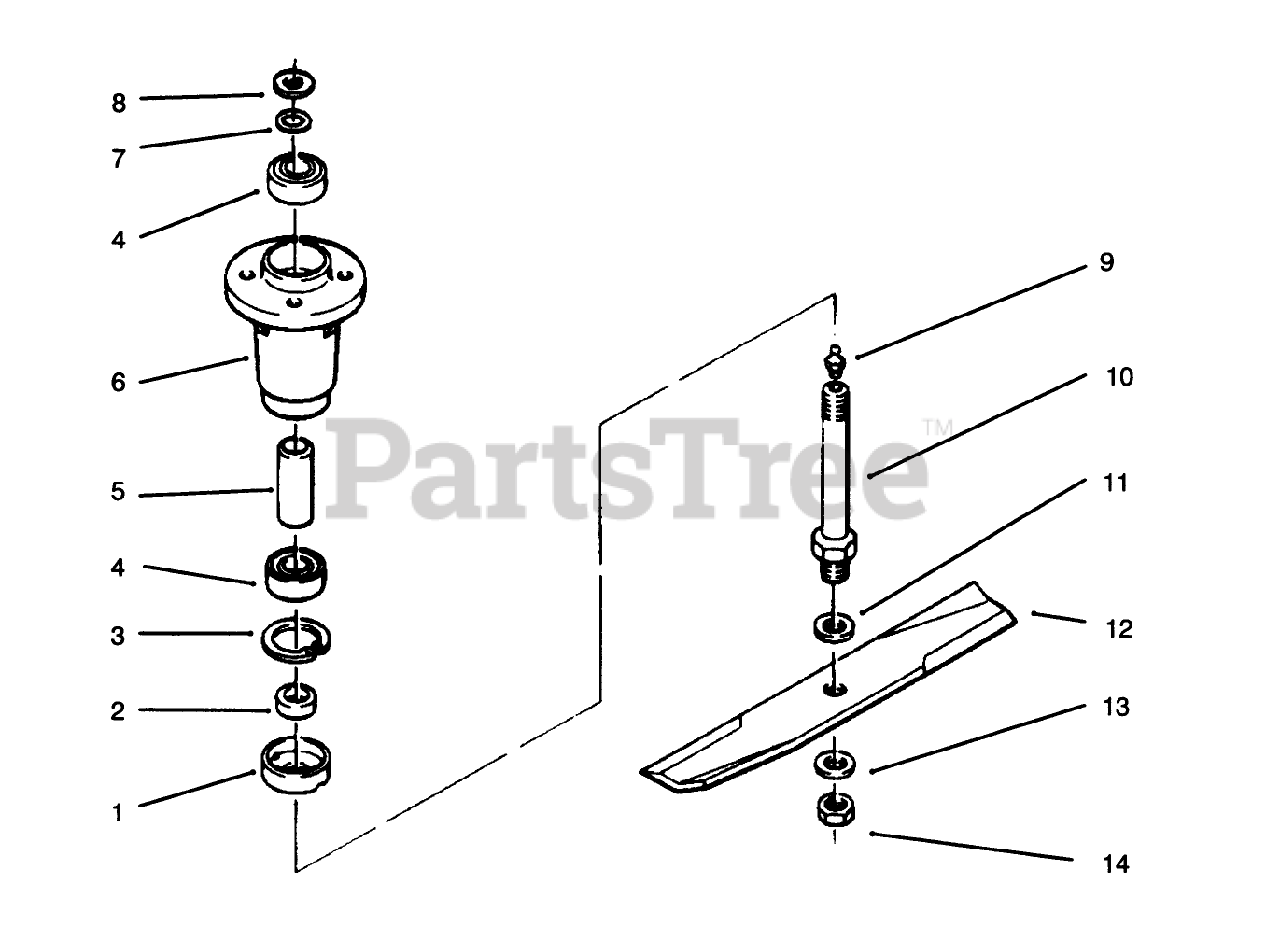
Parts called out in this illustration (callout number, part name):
2	SPACER-BLADE
3	RING-RETAINING
4	BEARING-BALL
6	HOUSING-SPINDLE
7	O RING
8	WASHER-FLAT
9	FITTING-GREASE
10	SHAFT-SPINDLE
11	WASHER-FLAT
12	S/A BLADE KIT
13	WASHER-FLAT
14	NUT-JAM
